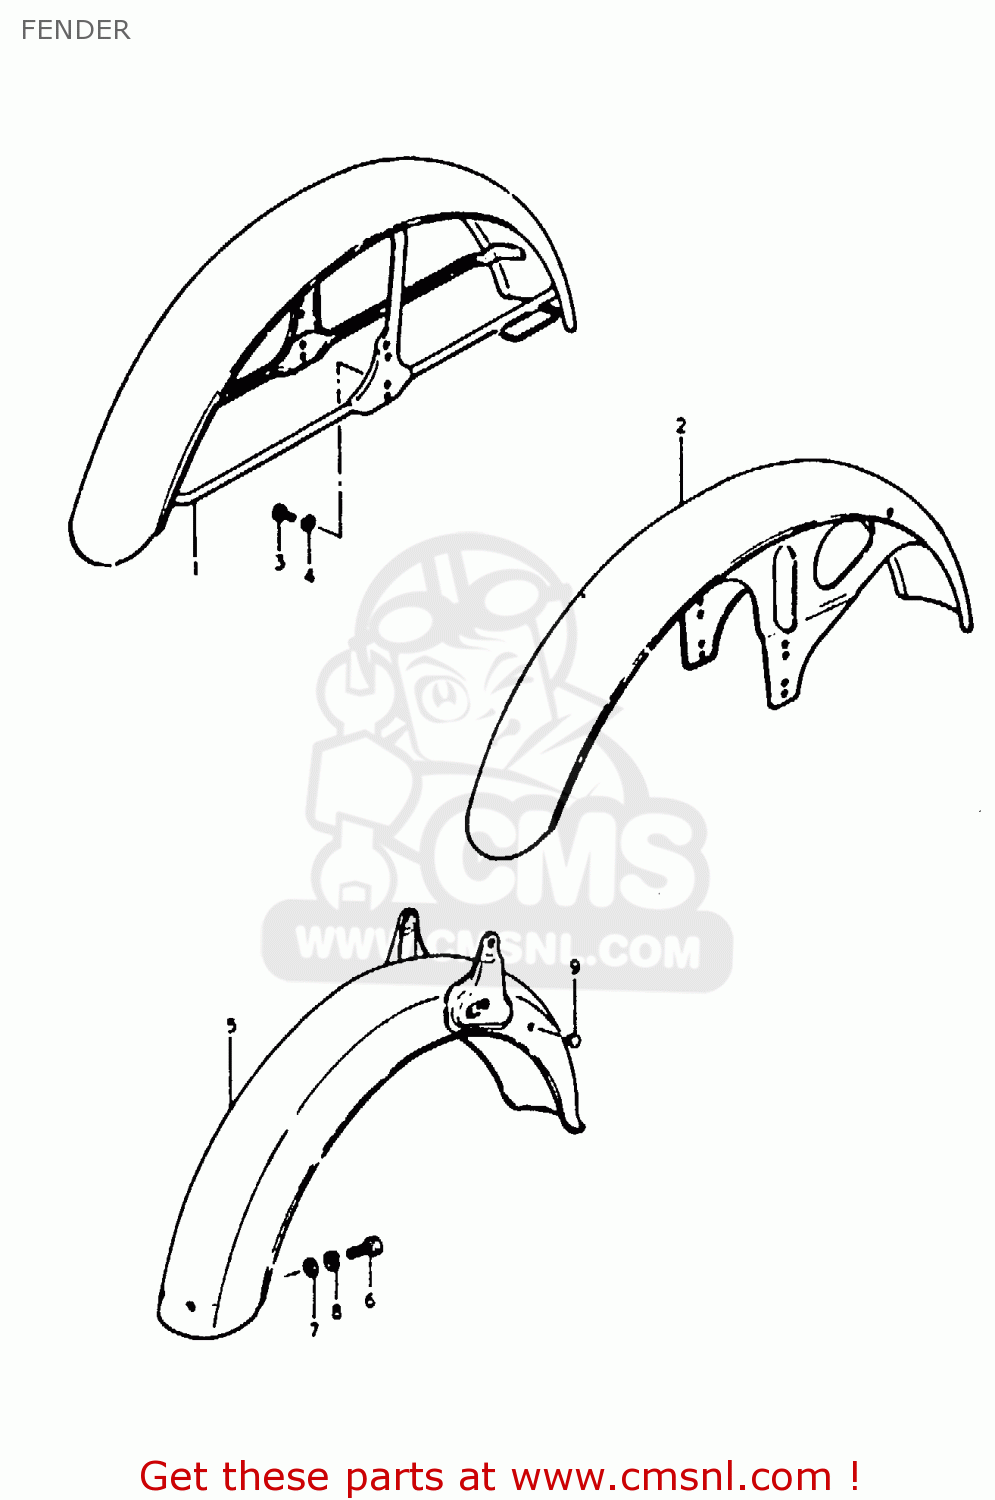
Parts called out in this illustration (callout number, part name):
1	FENDER,FRONT
3	BOLT
4	LOCK WASHER
5	FENDER,RR
6	BOLT
7	WASHER
8	LOCK WASHER
9	CAP(OD:10)
